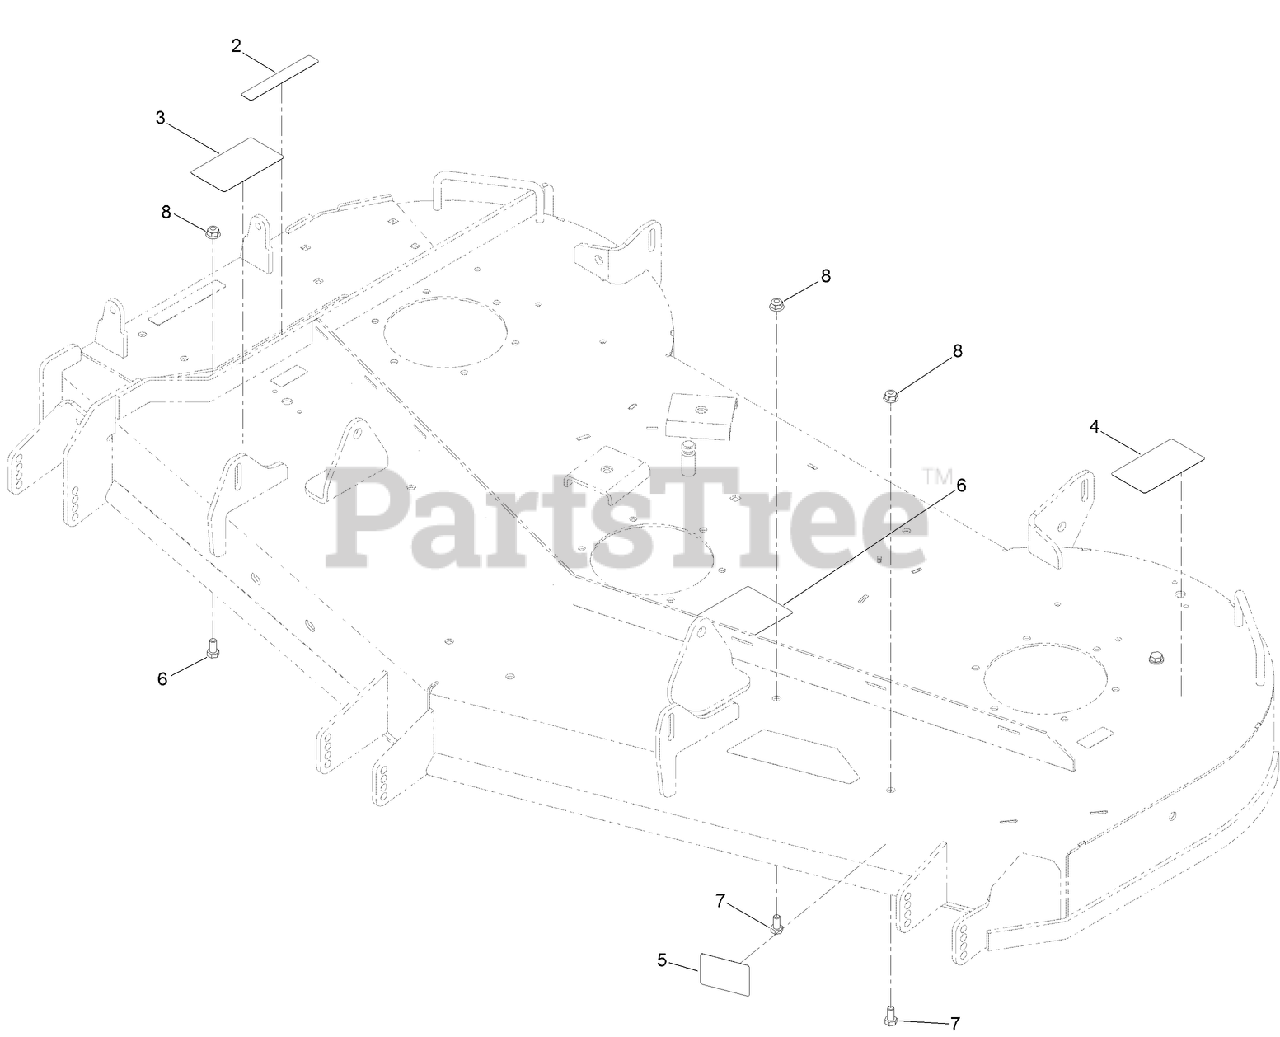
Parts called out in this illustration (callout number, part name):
2	DECAL-DANGER
3	DECAL-DANGER
4	DECAL-DANGER
5	DECAL-SCALP, ANTI
6	DECAL-ROUTING, BELT
7	SCREW-HH
8	NUT-HF, NI
